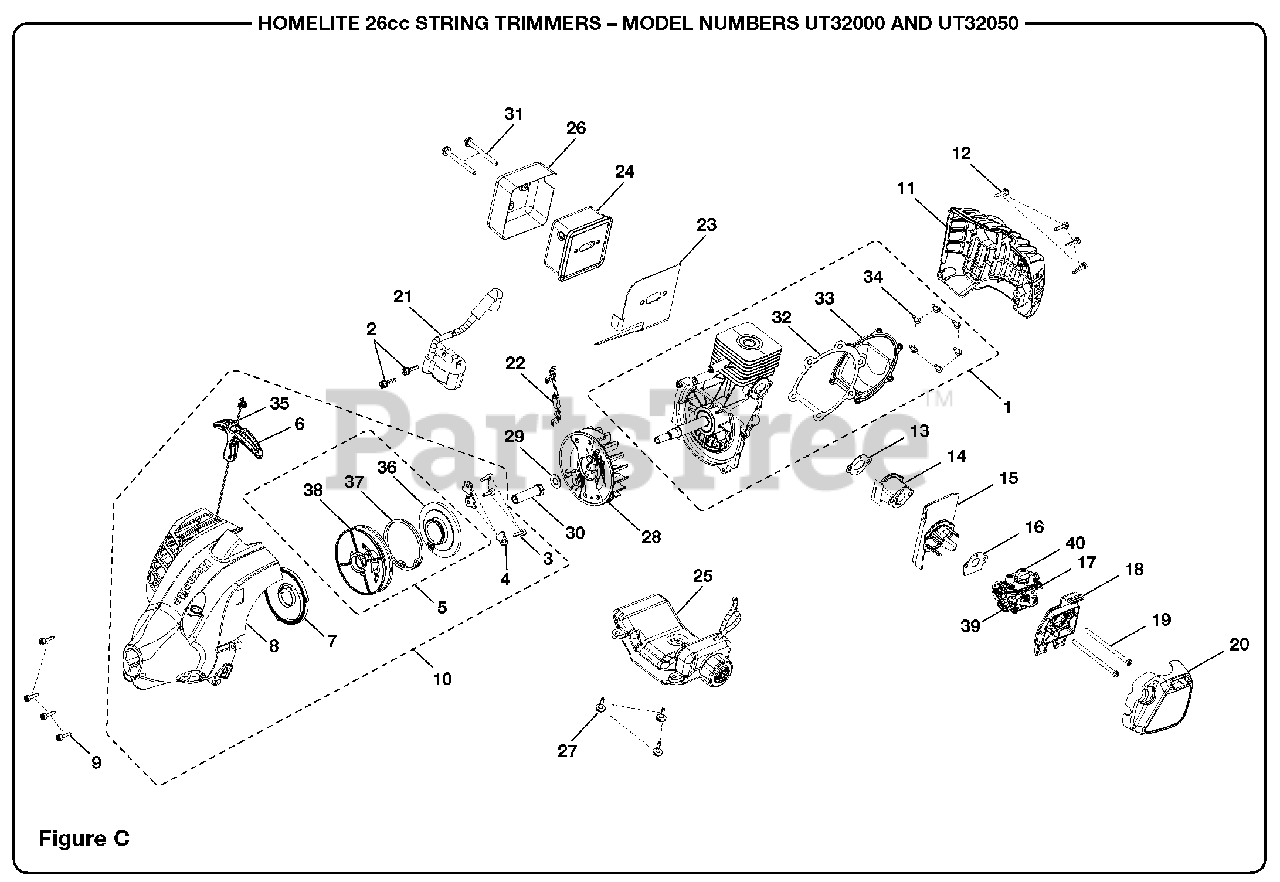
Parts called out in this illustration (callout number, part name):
1	Short Block Assembly (Inc. Key Nos. 32-34)
2	Screw (M4 x 19 mm)
3	Screw (M4 x 14 mm)
4	Pulley Retainer
5	Starter Pulley Assembly (Inc. Key Nos. 36-38)
6	Pulley Handle
7	Spring & Container Assembly
8	Front Housing
9	Screw (M4 x 16 mm)
10	Front Housing Assembly (Inc. Key Nos. 3-8; Plus Key Nos. 7, 10 and 11 from pages 2 & 4)
11	Rear Housing
12	Screw (M4 x 8 mm)
13	Intake Gasket
15	Heat Dam Deflector
16	Carburetor Gasket
17	Carburetor
18	Air Box Base
19	Screw (M5 x 70 mm)
20	Air Box Cover
21	Ignition Module
22	Lead Assembly
23	Muffler Gasket
24	Muffler Assembly
25	Fuel Tank Assembly w/Cap
26	Heat Shield
27	Screw (M4 x 10 mm, Shoulder)
28	Flywheel Assembly
29	Washer
30	Drive Connector
31	Screw (10-24 x 2-3/16 in.)
32	Gasket
33	Crankcase Cover
34	Screw (M4 x 12 mm)
35	Starter Rope (49 in.)
36	Starter Plate
37	Torsion Return Spring
38	Rope Pulley
39	Choke Lever
40	Primer Bulb
